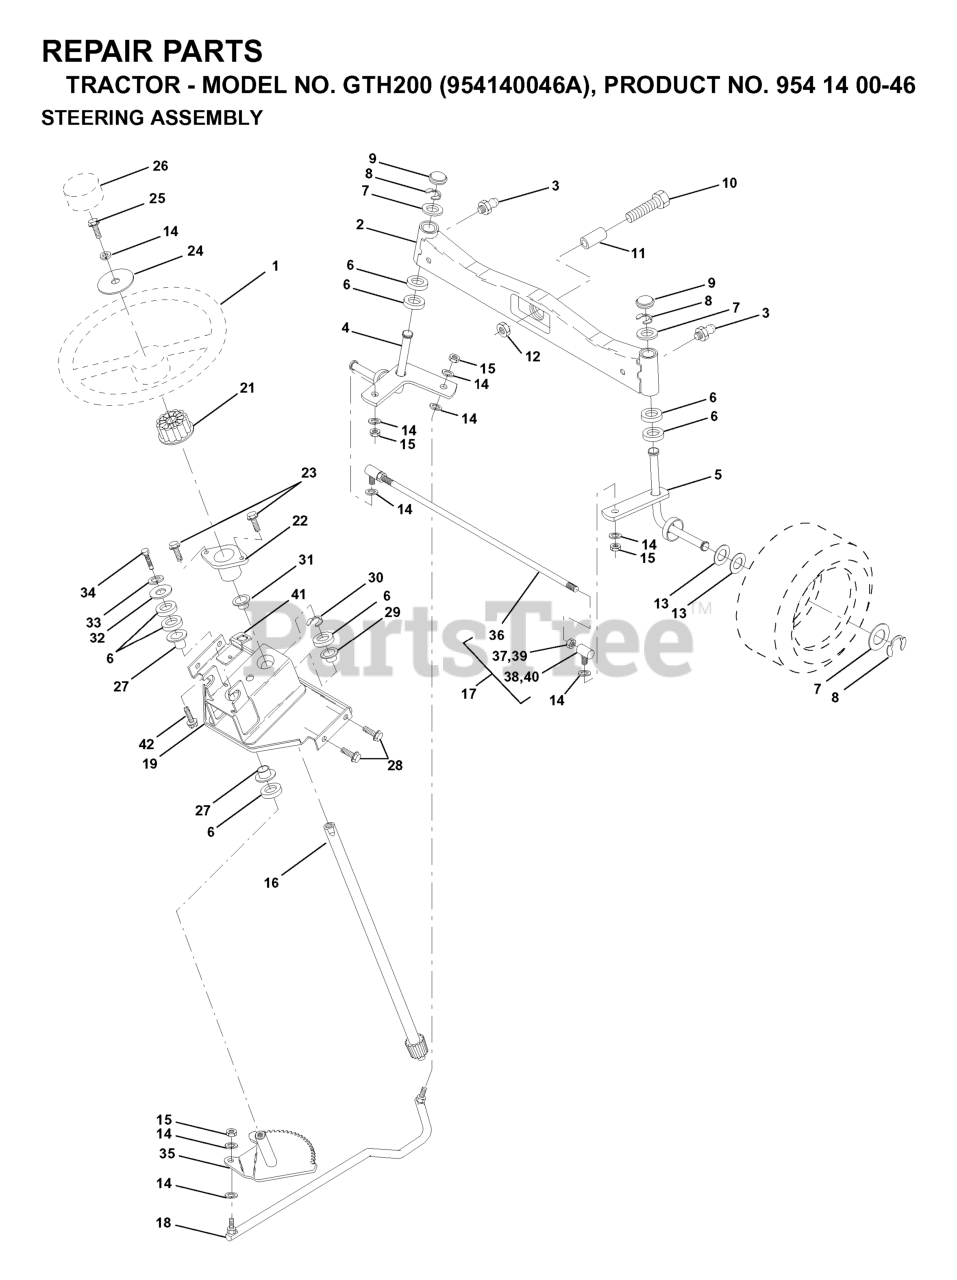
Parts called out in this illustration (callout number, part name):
1	STEERING WHEEL
2	FRONT AXLE ASSY
3	ZERK M
4	SPINDLE ASSY LH
5	SPINDLE ASM RH
6	THRUST WASHER
9	CAP.SPINDLE.BLACK
10	Bolt, Hex 5/8 -11 x 2 - 3/4 Gr. 5
11	TUBE, PIVOT AXLE
12	NUT-LOC,FLANGE LT
14	WASHER, LOCK 3/8
15	GRIPCO NUT
16	SHAFT ASM, STEERING
17	ROD ASSY/TIE BALL
18	DRAGLINK-BALL JOINT SOLID
19	SUPPORT ASM., STEERING VGT
21	ADAPTER LT
22	BUSHING, STRG. BLK
23	SCREW.TT.#10-32X.5.3/8.FLANGE
24	WASHER T
26	INSERT,STR WHEEL
27	BRNG T
28	SCREW
29	BEARING-FLANGE GT
30	Ring, Klip Truarc #5304-75
31	BUSHING.NYLINER.
33	WASHER.LOCK.HVY.HLCL.SPR.5/16
34	BOLT
35	GEAR.ASM.SECTOR.
36	TIE ROD
38	JOINT
41	BRACKET INTERLOCK
42	Screw 5/16-18 x 1/2 Hex, Self Tapping 5/16-18 x 1/2
